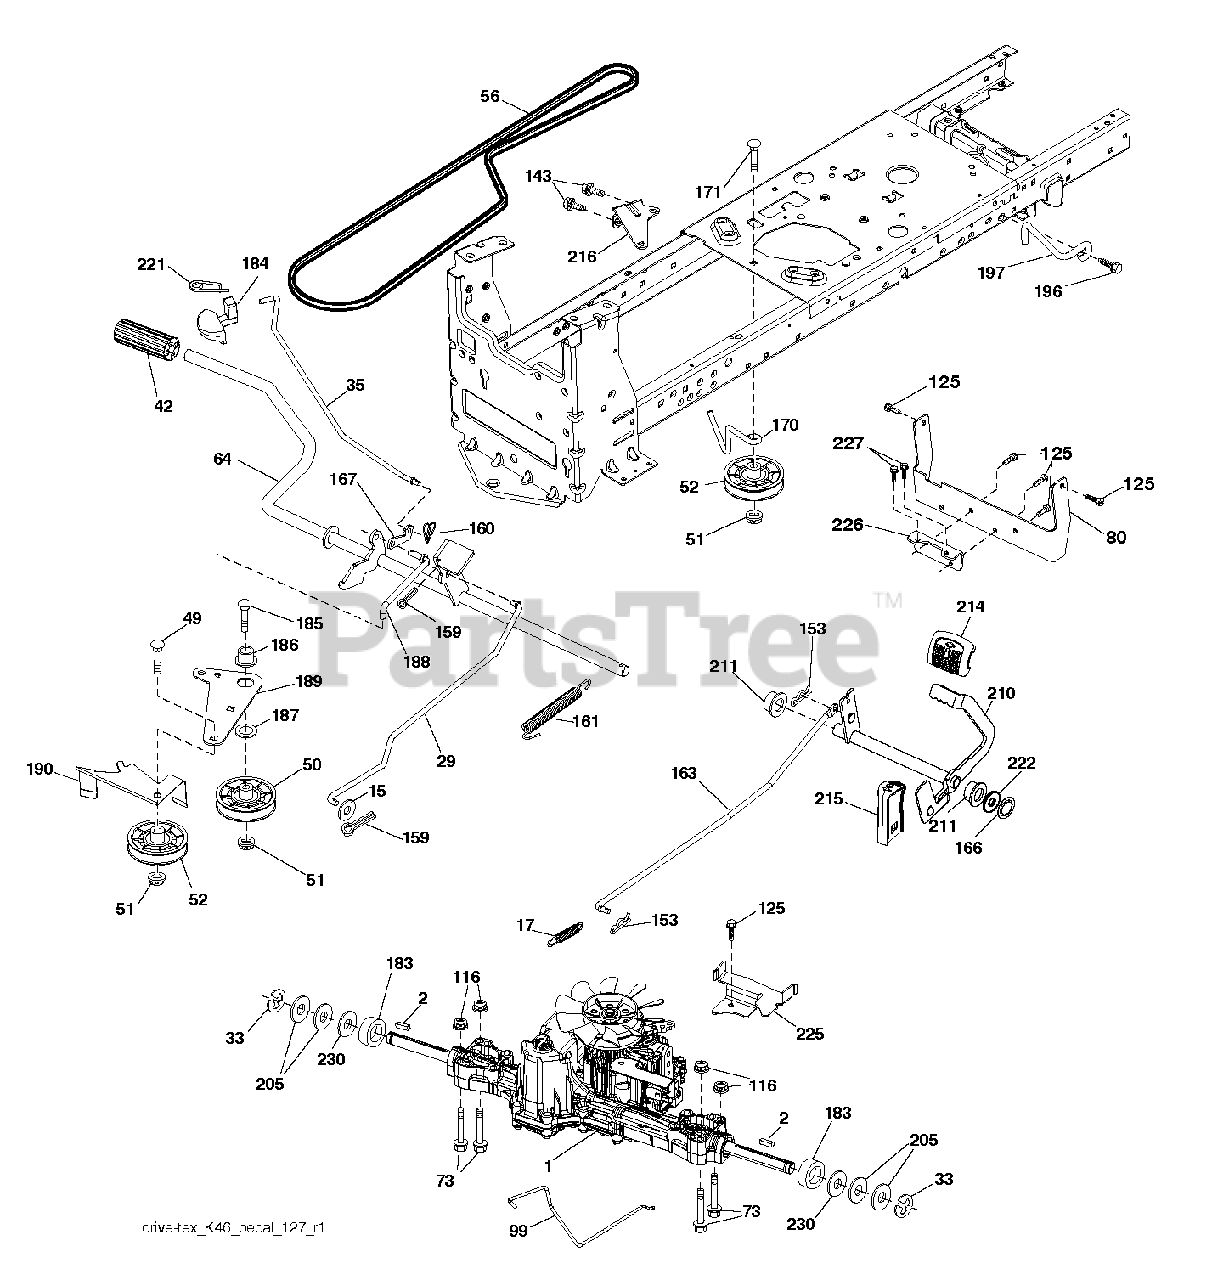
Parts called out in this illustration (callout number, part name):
2	SQUARE KEY
15	WASHER
17	SPRING.BRAKE.K46.GREEN
29	ROD.BRAKE.K46
35	ROD.CNTRL.PARK.PREDATOR.LT.TEX
42	PEDAL COVER T
50	IDLER.FLAT.910.OFFSET
51	NUT LOCK FLG 3/8-16 UNC
52	IDLER.V-GROOVE.910.OFFSET
56	V-BELT.MOWER.92.40.42/K46
64	SHAFT.ASM.PEDAL.BRK.CNTR
80	STRAP.TORQUE.K46.K57R.TT
99	ROD.SPRING.BYPASS.K46.LT.Z
116	NUT LOCK HEX FLANGE 5/16-18
125	SCREW
143	SCREW LT
153	RETAINER M
159	COTTER PIN
160	RETAINER CLIP
161	SPRING, RETURN LT
163	ROD.CONTROL.K57R.K46
166	NUT.PUSH.625
167	LATCH.BRAKE.SPRING
170	KEEPER.V-IDLER.CENTER.
183	SPACER AXLE
184	HANDLE.PARKING.BRK.PRED.LT.RED
186	SPACER.RETAINER
187	WASHER 12/32X2X10GA
188	RP LINK.CLUTCH.GROUND.DRIVE
189	BELLCRANK.GROUND.DRIVE.TEX.
190	KEEPER.BELLCRANK.DRIVE
196	SCREW 3/8-16X1
197	LINK.CLUTCH.ANIT-ROTAT
210	ROCKER.ASM.PEDAL.CONTR
211	BEARING.NYLON
214	PEDAL.FORWARD.PAD.TEX
215	PEDAL.REVERSE.TEX.GT.4
216	BRACKET.PULLEY.IDLER.W/TEX
221	RETAINER.SPRING.CLIP.H
222	WASHER 21/32 X 1-1/4 X 10 GA.
225	KEEPER.BELT.TRANSAXLE.K46
226	BRACKET.MOUNT.TORQUE.K46.TLT
227	SCREW
230	WASHER.HARDENED
